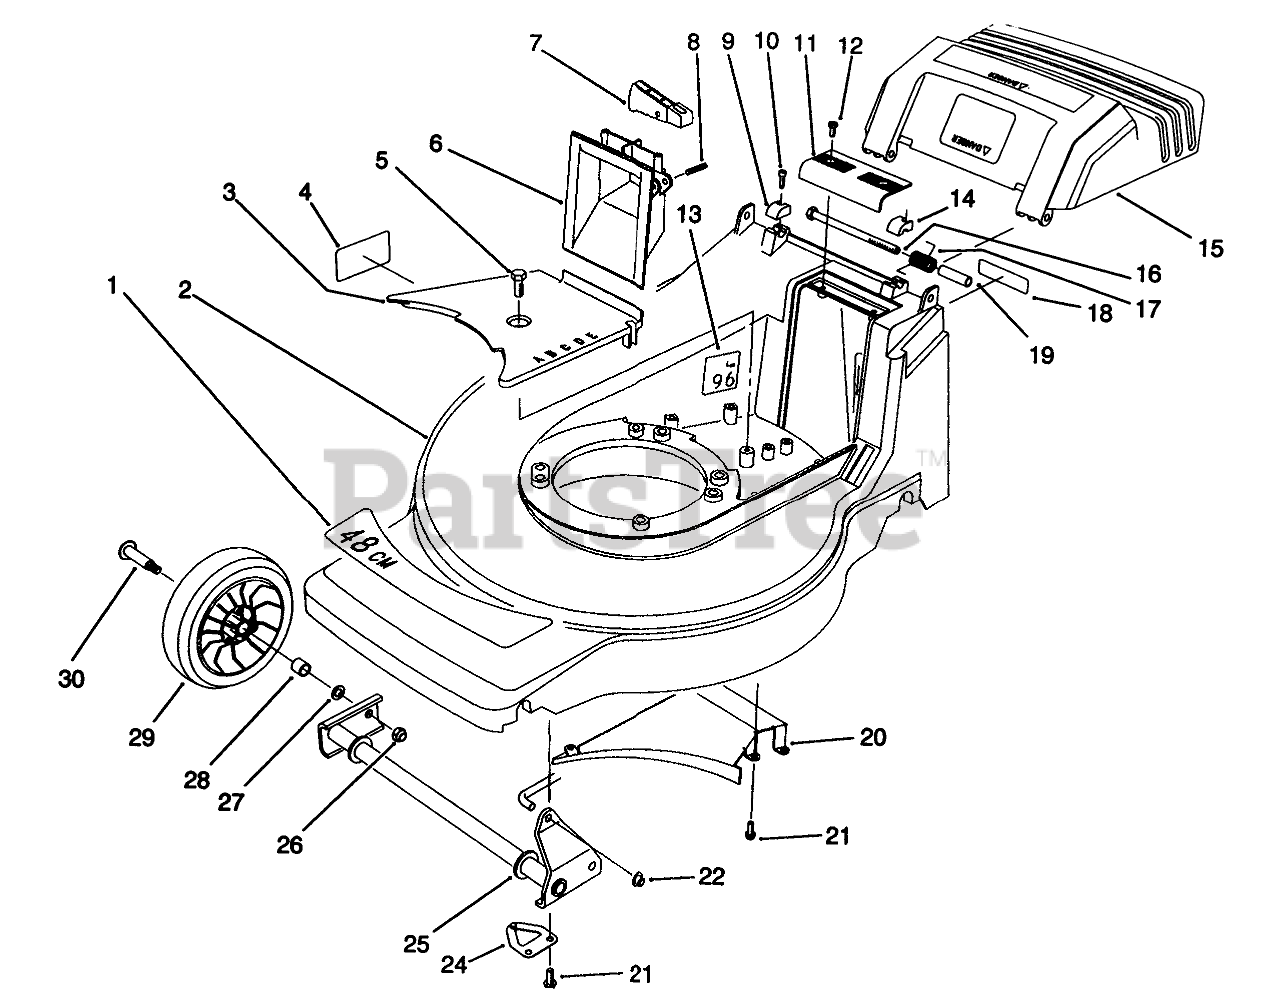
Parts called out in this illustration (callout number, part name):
1	DECAL - DECK
2	Housing-48cm
3	BELT COVER
4	Decal Danger
5	SCREW-HWHTF
6	GRIP - LOWER
7	TRIGGER - HOC
8	PIN-SPIRAL
9	CAP-HINGE BOLT, RH
10	SCREW-HSH
11	GRIP-UPPER
12	SCREW-PPH, PLASTITE
13	Decal-Noise
14	CAP-HINGE BOLT, LH
15	HP DISCHARGE DOOR
16	SCREW-HH
17	DOOR SPRING
18	DECAL FRENCH REGUL.
19	SPACER-DOOR
20	Ramp-Discharge
21	SCREW-HWH
22	NUT-PUSH
24	SHAFT RETAINER ASM
25	FRONT PIVOT WA
26	NUT-HEX
27	WASHER
28	BUSHING
29	Wheel & Tire Assembly (Incl. Ref. #28)
30	BOLT-WHEEL
